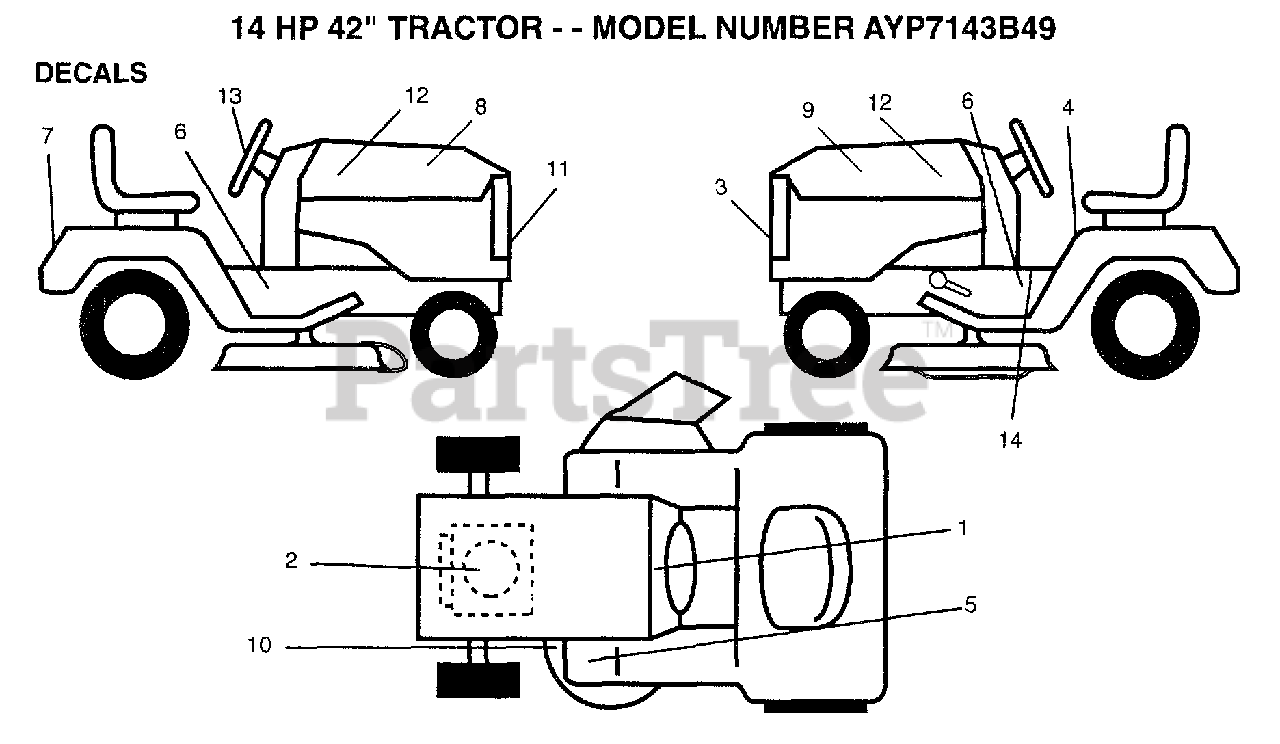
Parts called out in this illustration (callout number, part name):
1	DECAL.DASH.INST.
2	DECAL.ENG.272750
3	DECAL GRILL WIZ
4	DECAL
6	DECAL CHASSIS WIZ
8	DECAL HOOD RH WIZ
9	DECAL HOOD LH WIZ
10	DECAL
11	DECAL GRILL WIZ
12	DECAL HOOD INSERT
14	DECAL BRAK PARK
